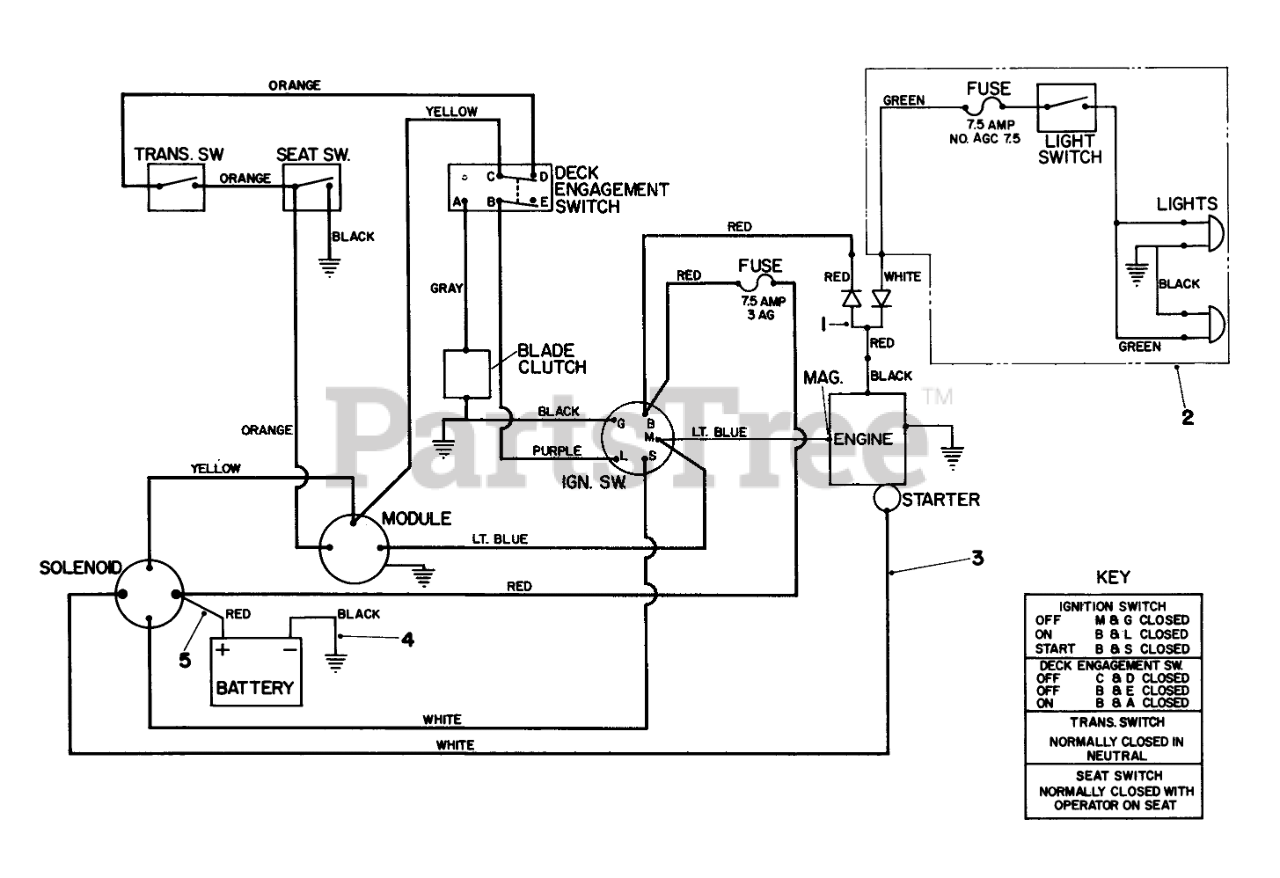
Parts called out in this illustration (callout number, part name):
1	WIRE HARNESS WIRE
2	WIRE HARNESS
3	WIRE HARNESS
4	WIRE ASM
5	WIRE ASM
